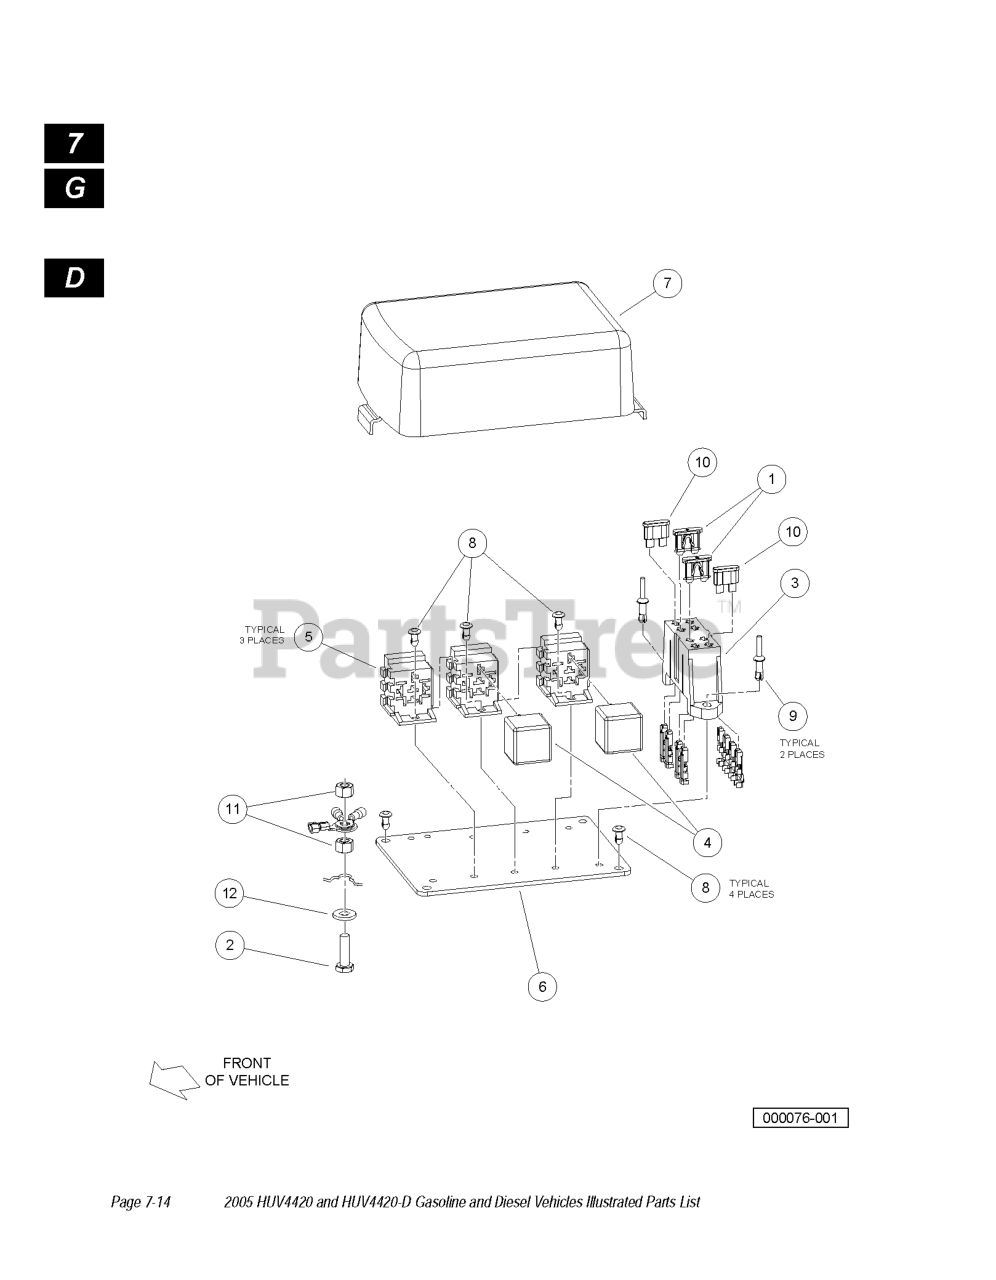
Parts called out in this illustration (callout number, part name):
1	10 AMP FUSE
3	FUSE BLOCK
4	RELAY, MINI ISO, SPDT
6	PLATE, ELECTRICAL
7	COVER, ELECTRICAL
8	FASTENER, PUSH-IN
9	RIVET, DRIVE
10	FUSE, ATC/ATO, 25A
11	LOCKNUT, 1/4-20 DIMPLED
12	WASHER 1/4 FLAT
